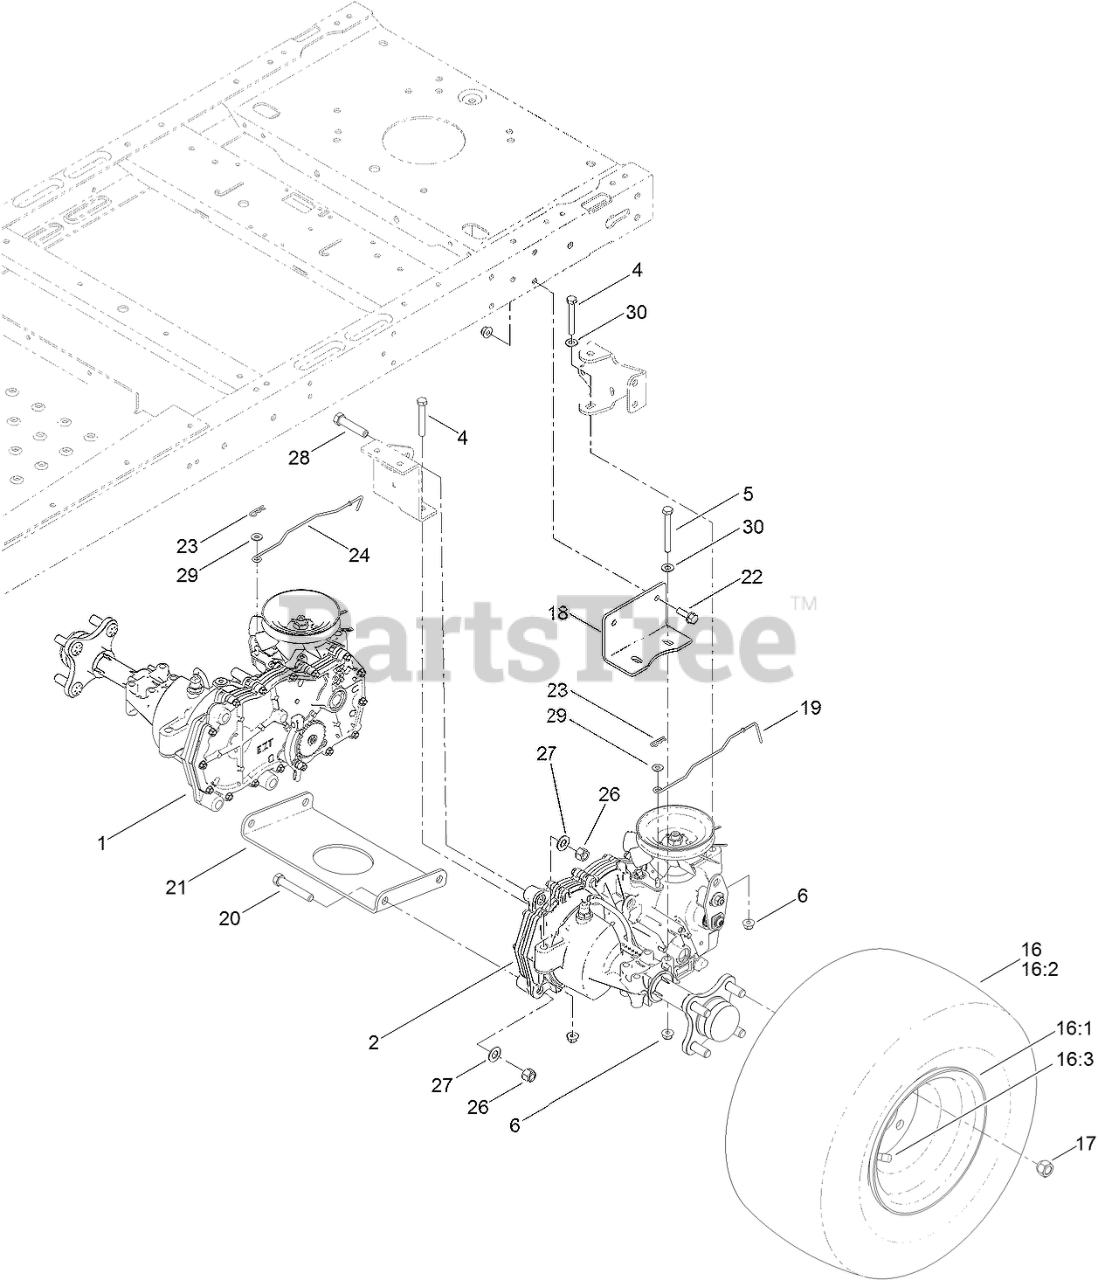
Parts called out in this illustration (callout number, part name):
1	RH HYDRO TRANSAXLE ASM
2	LH HYDRO TRANSAXLE ASM
4	SCREW-HH
5	SCREW-HH
6	NUT-HF, NI
16	4 PLY WHEEL AND TIRE ASM
16:2	TIRE-4 PLY
16:3	STEM-VALVE
17	NUT-LUG
18	MOUNT-HYDRO
19	ROD-BYPASS, LH
20	SCREW-HH
21	PLATE-CROSS, HYDRO
22	SCREW-HHF
23	PIN-COTTER
24	ROD-BYPASS, RH
26	NUT-LOCK, NI
27	WASHER-FLAT
28	SCREW-HH
29	WASHER-FLAT
30	WASHER-PLAIN
